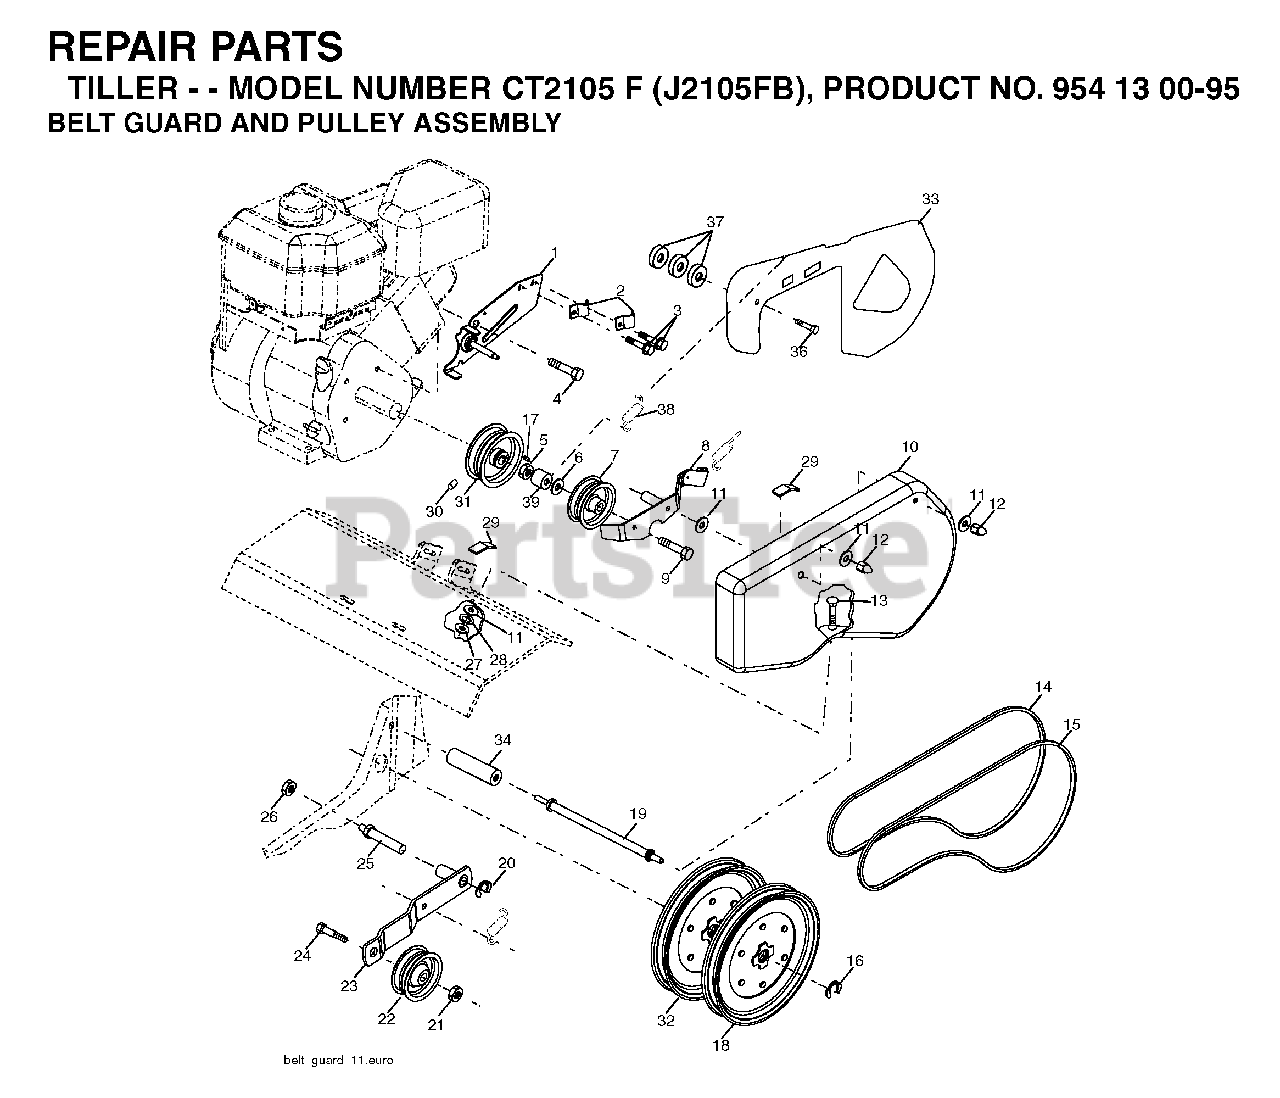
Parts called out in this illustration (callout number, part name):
1	RP BRKT.ASM.GUARD.BELT
2	CONDUIT CLIP T
3	TAPPING SCREW
5	LOCKNUT
7	PULLEY
8	ARM
9	BOLT
11	WASHER
12	CAP
15	BELT
16	RETAINING RING LT
18	SHEAVE,TRANS."D"
19	BOLT.BELT.GUARD
20	KLIP RING TI
21	NUT
22	PULLEY, IDLER
23	ARM, IDLER
25	SHAFT.IDLER.TILLER
26	JAM NUT TI
27	NUT
28	LOCKWASHER
29	PAD IDLER TI
32	SHEAVE.TRANS
37	WASHER
38	SPRING.EXTENSION
